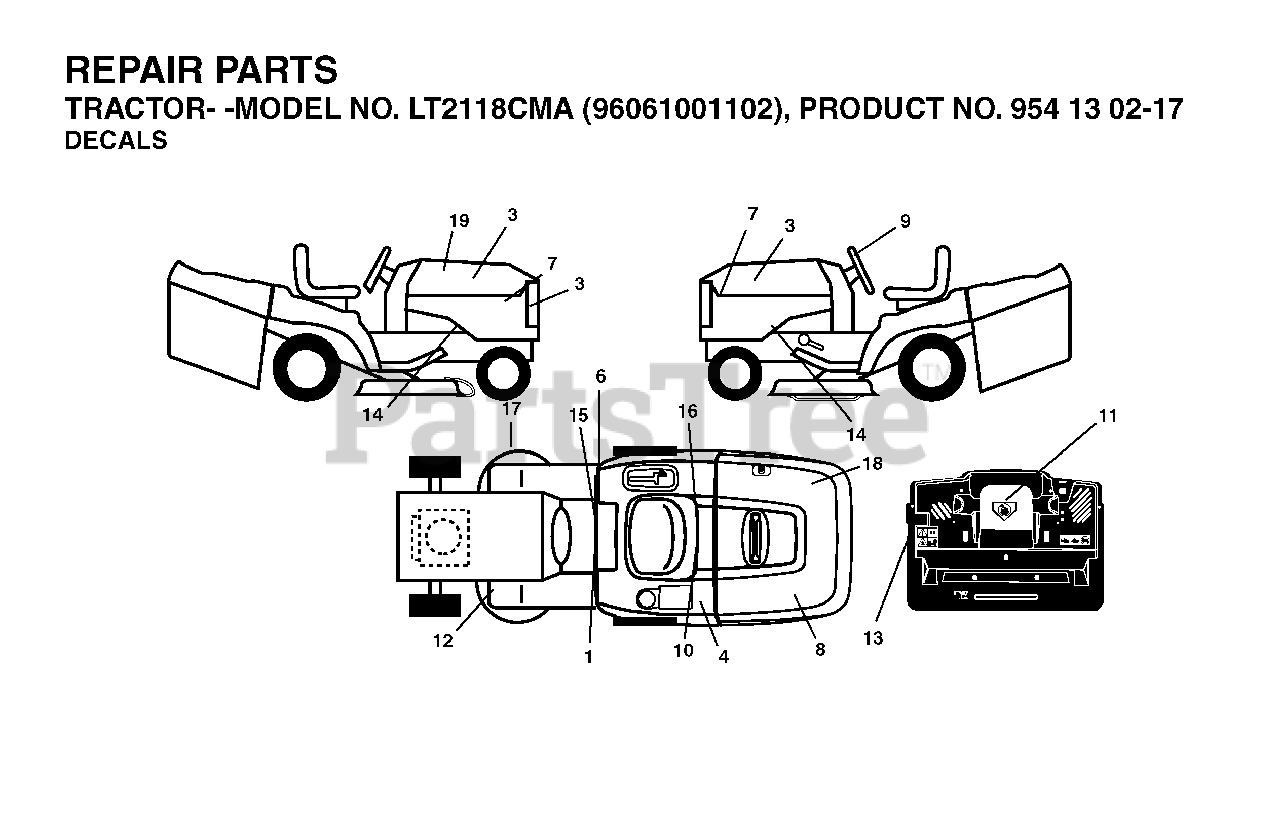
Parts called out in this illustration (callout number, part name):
1	DECAL READ OWNER'S MAN SYMS
10	DECAL BTRY SYMBOLS
11	DECAL.INTERNATIONL.CUTFINGER
15	DECAL PARK BRAKE
16	DECAL.BYPASS.FENDER.CRD.LT.YT
